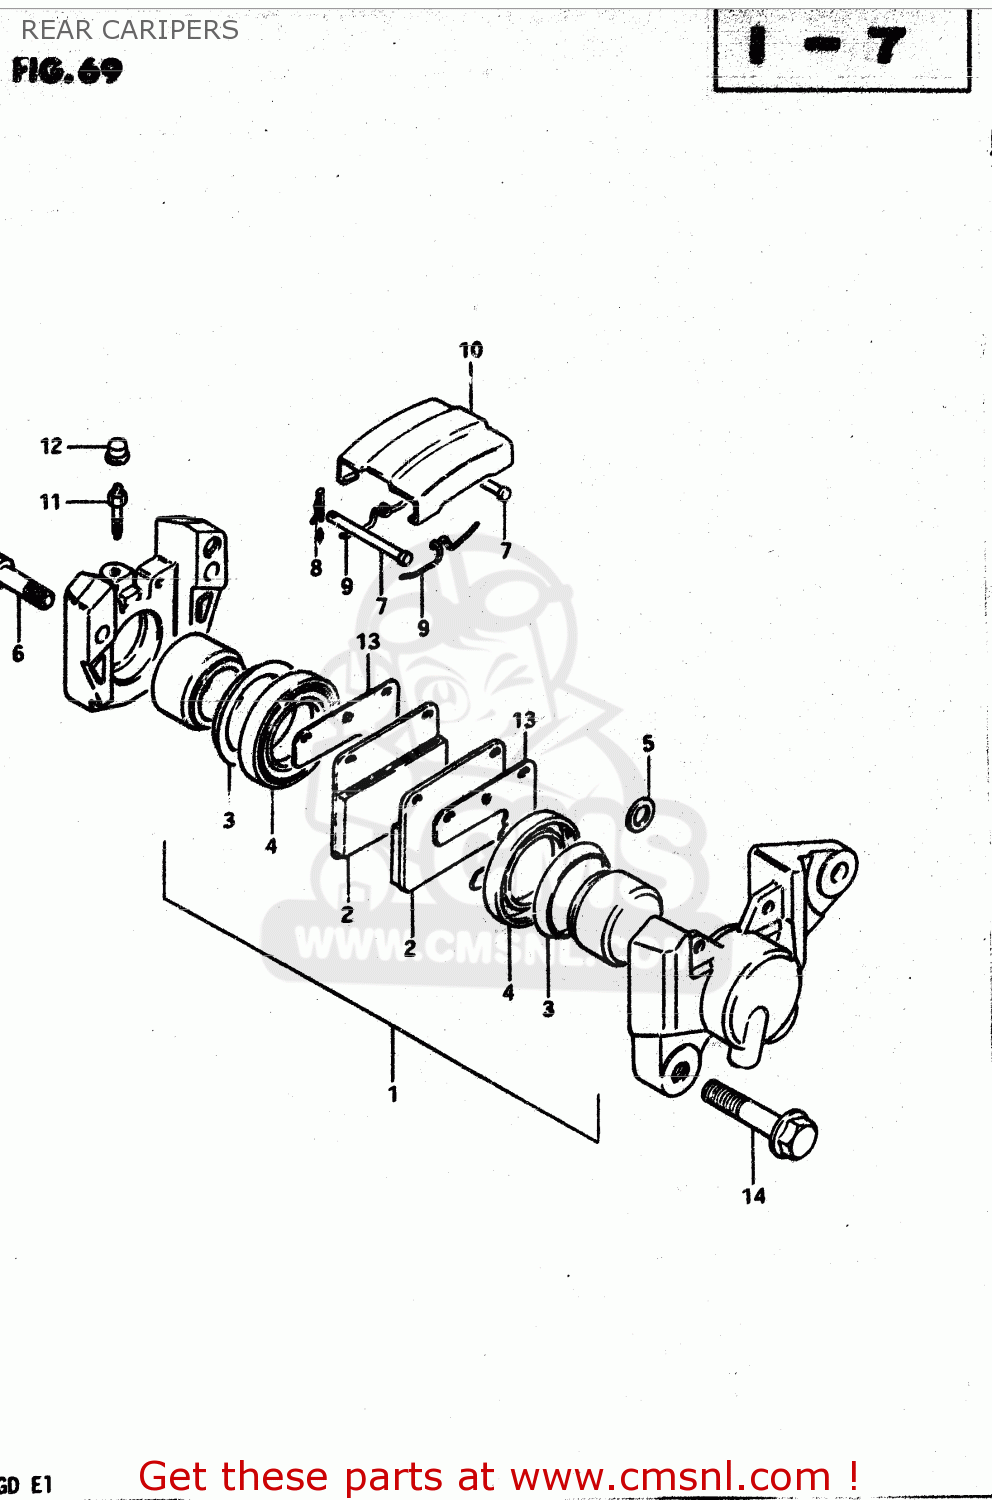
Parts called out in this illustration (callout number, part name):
1	PISTON SET
2	PAD,BRAKE
3	SEAL,PISTON
4	BOOT,PISTON
5	SEAL,JOINT
6	BOLT,CALIPER HOUSING
7	PIN,PAD
8	CLIP,PAD PIN
9	SPRING
10	COVER,DUST
11	BLEEDER
12	CAP,BREATHER
13	SHIM,RR CALIPER
14	BOLT
